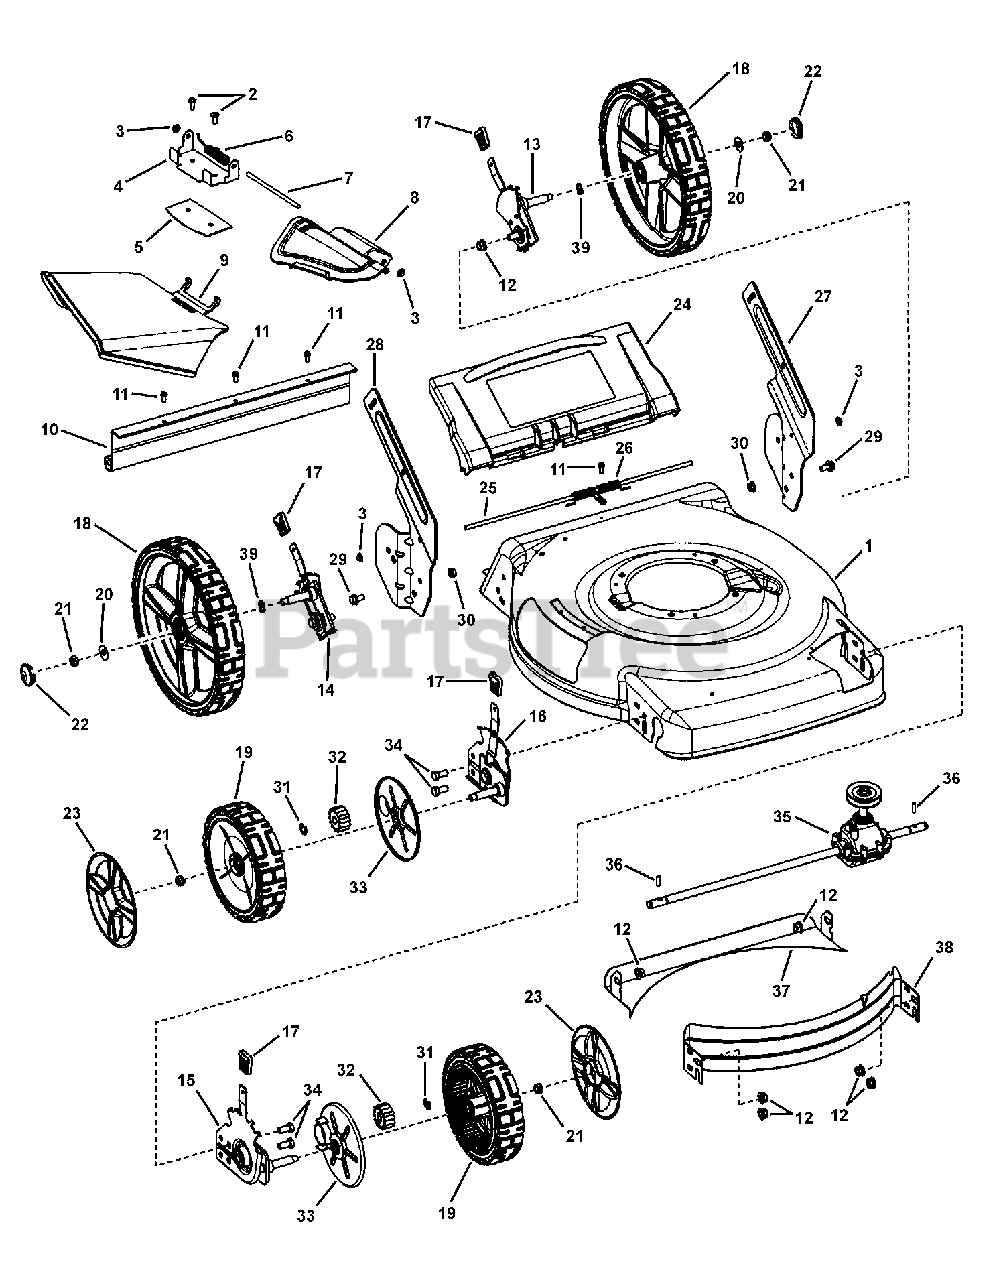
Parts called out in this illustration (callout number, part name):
1	DECK, 22" Walk, 3-N-1
2	SCREW, 1/4-20 x 11/16" Pan Head Torx, Self-Tap
3	PUSHNUT, 1/4"
4	BRACKET, Chute
5	PLATE, Mulch, 22" RB Scotts
6	SPRING, Torsion, Chute
7	ROD, Pivot
8	COVER, Mulch, Plastic, Black
9	SIDE CHUTE, Plastic, Black
10	GUARD, Rear
11	SCREW, #10-24 x 1/2" Hex Washer Self-Tap, SEMS
12	NUT, 3/8-16 Hex Flange Lock, YZ
13	ASSEMBLY, Height-Of-Cut, Left Rear, 22" WBM
14	ASSEMBLY, Height-Of-Cut, Right Rear, 22" WBM
15	ASSEMBLY, Height-Of-Cut, Left Front, 22" WBM, Propelled
16	ASSEMBLY, Height-Of-Cut, Right Front, 22" WBM, Propelled
17	GRIP, Height Latch - Black (1.3" Wide)
18	ASSEMBLY, Wheel, 12 x 2 Idle, BB, Snapper Cool Gray
19	ASSEMBLY, Drive Wheel, 8 x 2, BB, Snapper Charcoal Gray
20	WASHER, 1" OD x .387 ID, Flat
21	NUT, 3/8-16 Hex Center Lock, YZ
22	HUBCAP, 12" Wheel, Snapper Cool Gray
23	HUBCAP, 8" & 9" Wheel Spoked, Snapper Cool Gray
24	DOOR, 22" Rear
25	ROD, Pivot, Rear Door
26	SPRING, Torsion, Rear Door, 22" WBM
27	BRACKET, Lower Handle, LH, 22" WBM, HW
28	BRACKET, Lower Handle, RH, 22" WBM, HW
29	BOLT, 5/16-18 x 5/8" Hex Flange Lock, YZ
30	NUT, 5/16-18 Hex Flange Lock, GR 5, YZ
31	RETAINING RING
32	GEAR, Pinion, 22" WBM, FWD
33	DUST SHIELD, 22" WBM, FWD
34	SCREW, 3/8-16 x 3/4" Hex Head Cap, GR 5, YZ
35	TRANSMISSION, Rocker, 22" WBM HW, VS
36	PIN, Drive, 22" WBM, FWD
37	BAFFLE, Rear, 22" Deck
38	BAFFLE, Front, 22" WBM
39	WASHER, .531 x .781 x 3-Wave
